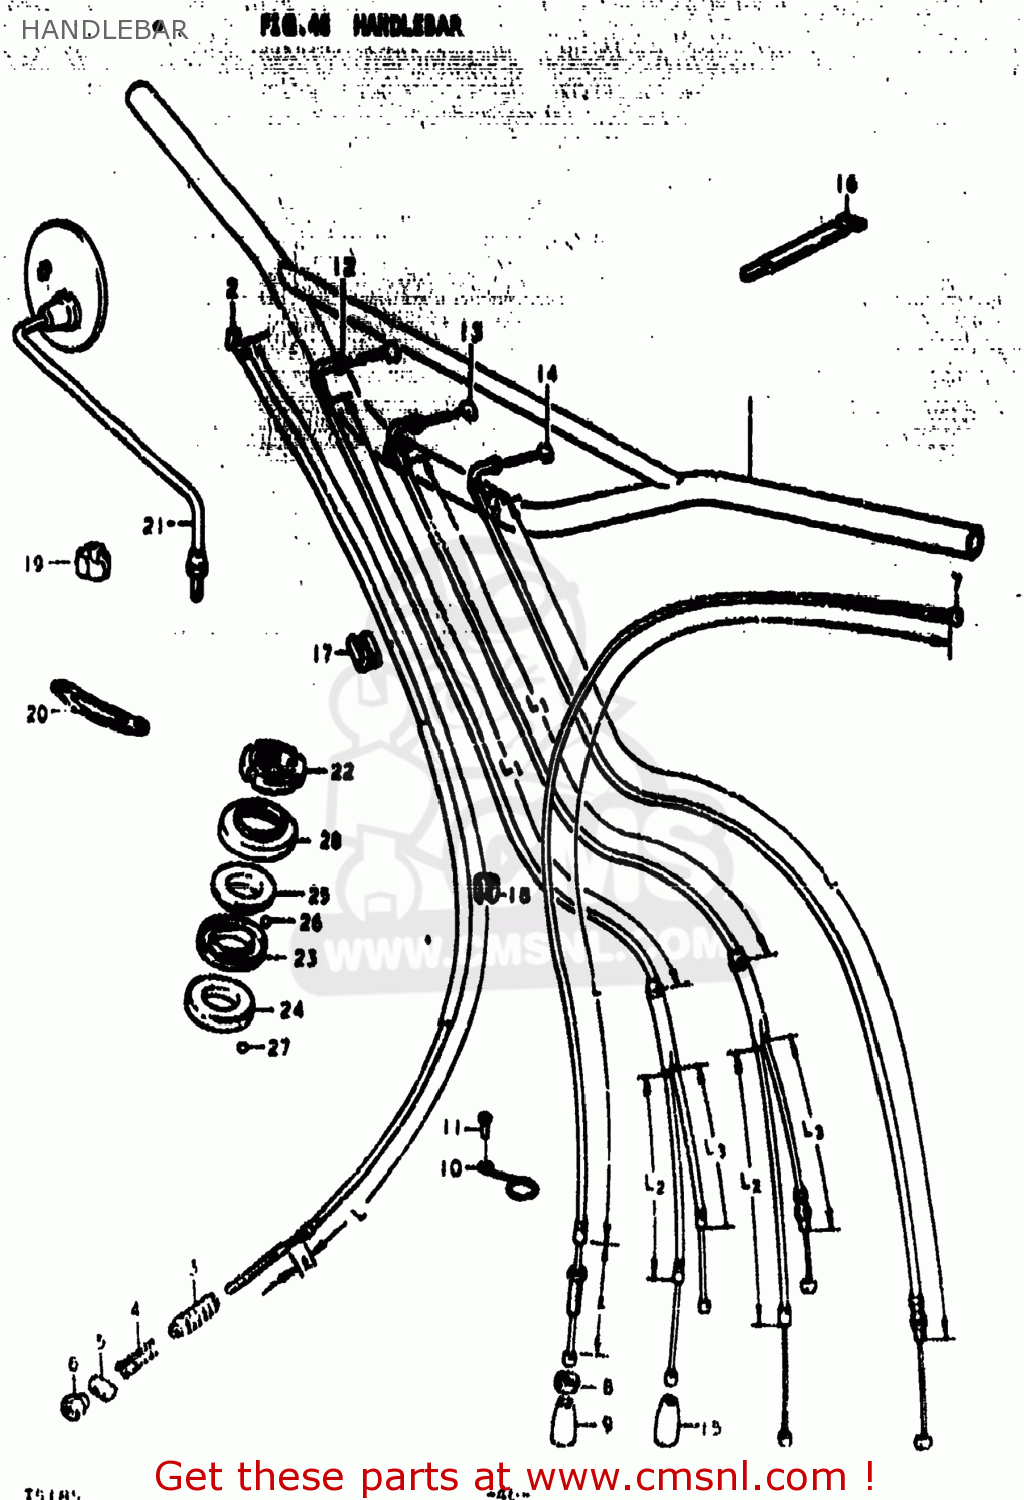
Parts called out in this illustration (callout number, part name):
1	HANDLEBAR
2	CABLE ASSEMBLY,FRONT BRAKE
3	SEAL,DUST(7X16X75)
4	SPRING
5	PIN,10X19
6	NUT
7	CABLE ASSY,CLUTCH
8	NUT
9	SEAL,DUST(7X18X30)
10	CLIP
11	SCREW
12	CABLE ASSEMBLY,THROTTLE
13	CABLE ASSY,THROTTLE NO.1
14	CABLE ASSEMBLY,THROTTLE
15	SEAL,DUST(7X18X30)
16	CLAMP
17	CLIP
18	CLIP
19	CLAMP
20	GUIDE,CABLE
21	MIRROR ASSEMBLY,LEFT
22	NUT,STEERING STEM(25X44X10)
23	RACE,STEERING INNER UPR
24	LACE,STEERING INNER LWR
25	RACE,STEERING OUTER UPR
26	BALL
27	BALL
28	DUST SEAL,STEERING UPR
